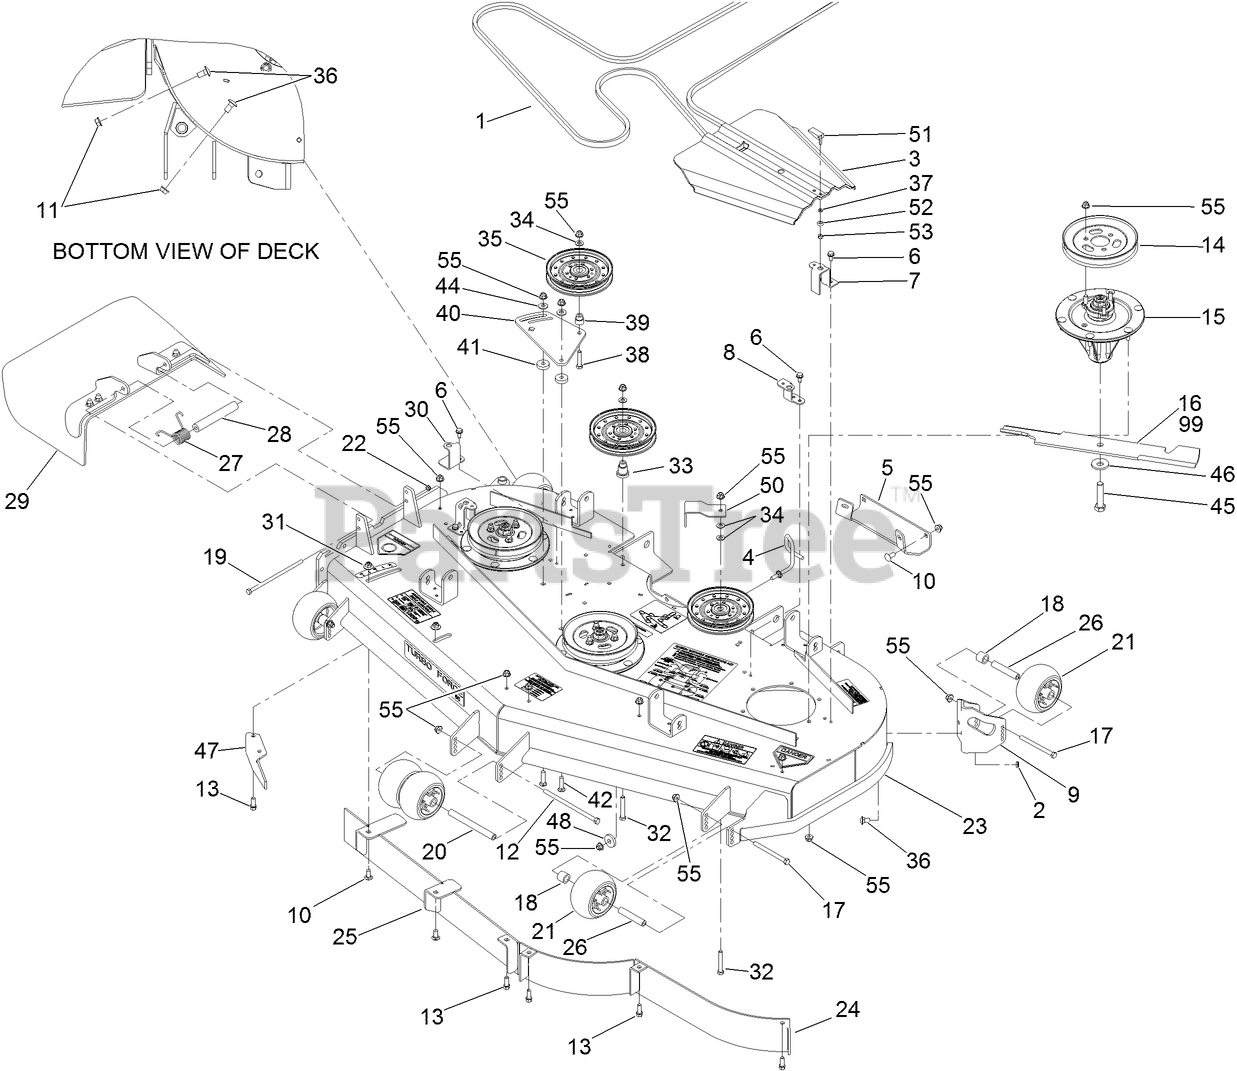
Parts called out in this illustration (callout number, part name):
2	NUT-LOCK, NI
3	COVER-BELT
4	GUIDE-BELT
5	Plate-Skid
6	SCREW-HWHTF
7	BRACKET-COVER
8	BRACKET-COVER, TALL
9	MOUNT-WHEEL, LH
10	SCREW-CARR
11	NUT-HHF, WHIZ
12	SCREW-HH
13	SCREW-HWH
14	Pulley
15	SPINDLE ASM
16	BLADE-HI FLOW
17	SCREW-HH
18	TUBE-SPACER
19	SCREW-HH
20	SPACER-WHEEL
21	ROLLER-SCALP, ANTI
22	NUT-LOCK, NI
23	DECK DECAL ASM
26	TUBE-SPANNER
27	SPRING-TORSION
28	SPACER
29	RUBBER DEFLECTOR ASM
30	BRACKET-COVER
31	NUT-FLANGE, NI
32	SCREW-HH
33	MOUNT-PULLEY
34	WASHER-FLAT
35	Idler-Flat
36	SCREW-CARR
37	WASHER
38	SCREW-HH
39	BUSHING-IDLER
40	Plate-Idler
41	Spacer
42	SCREW-CARR
44	WASHER-BELLEVILLE
45	SCREW-BLADE
46	Washer-Blade Bolt, Heavy
47	BAFFLE-DISCHARGE
48	WASHER
50	GUIDE-BELT
51	HANDLE-LATCH, SWELL
52	BUSHING-LATCH, SWELL
53	NUT-LOCK, HH
55	NUT-HF, NI
99	BLADE-MID FLOW, 20.5 INCH
99	BLADE-LO FLOW, 20.5IN
99	BLADE-RECYCLER, 20.5 INCH
99	BLADE-ATOMIC, 20.5IN
